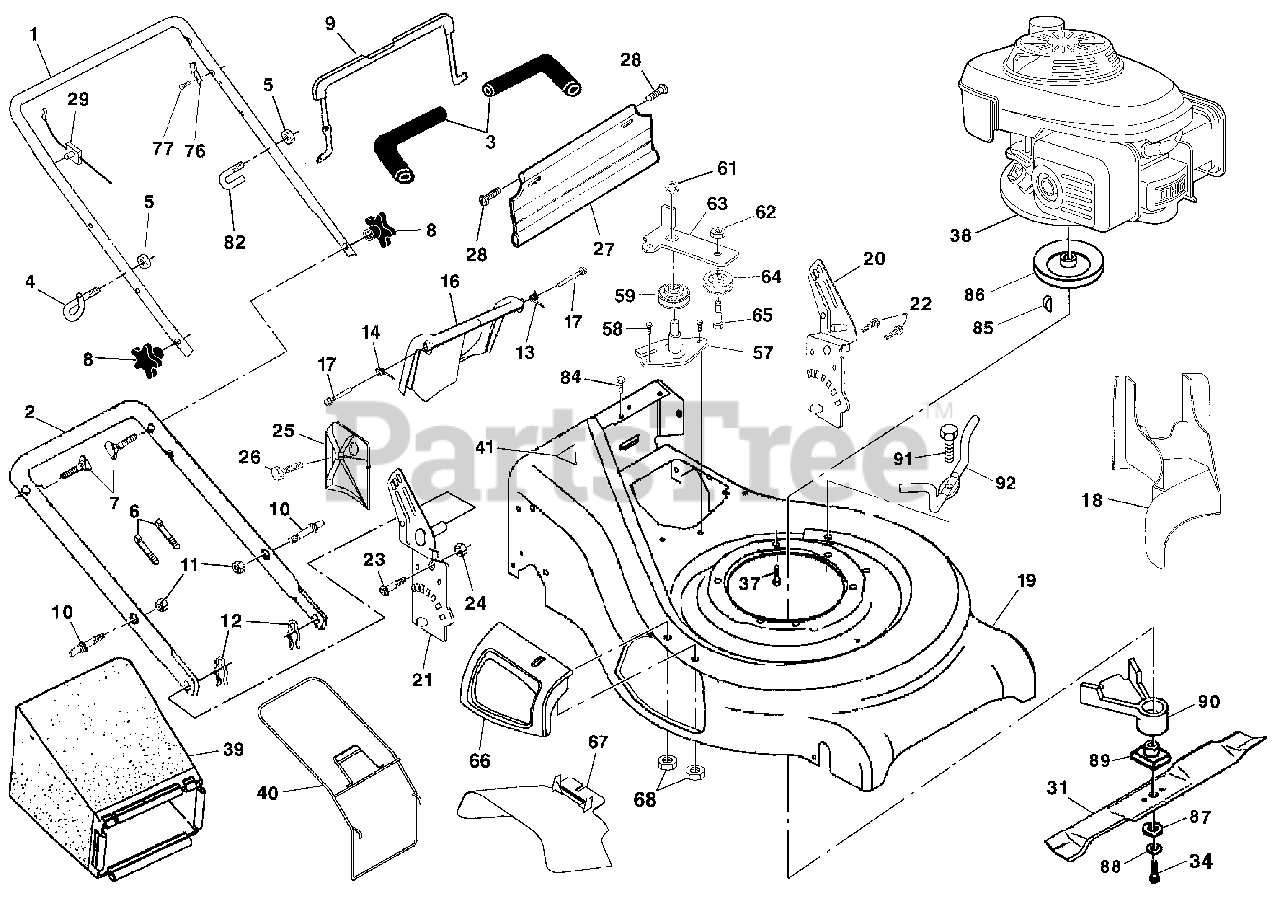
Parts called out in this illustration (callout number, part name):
1	Handle, Upper
2	Handle, Lower
3	Grip, Handle, Foam, Smooth
4	Guide, Rope, Side
5	Nut, Hex Lockwasher Insert 1/4-20
6	Wire, Tie
7	Bolt, Handle 5/16-18 x 1.75
8	Knob, Handle
9	Bail, Flat, Auto-Walk, Orange
10	Bolt, Carriage
11	Nut, Hex, Centerlock 5/16-18 UNC
12	Cotter, Hairpin
13	Spring, Rear Door, LH
14	Spring, Rear Door, RH
17	Bolt, Rear Door
18	Plug, Mulcher
19	Kit, Housing
20	Handle Bracket Assembly, LH
21	Handle Bracket Assembly, RH
22	Screw, Hex Washer Head
23	Bolt, Hex Head 5/16-18 x 5/8
24	Nut, Hex, with Lock Washer Insert 5/16-18
25	Baffle, Side
26	Screw 12 x 5/8
27	Skirt, Rear
28	Screw, Hinge 1/4-20 x 1.25
29	Engine Zone Control Cable
31	Blade, 21"
34	Screw, Hex Head 3/8-24 x 1.38
37	Bolt, Engine
39	Grass Catcher Bag
40	Grass Catcher Frame
41	Danger Decal
57	Bracket Assembly
59	Pulley Assembly, V-Groove
61	Flange Nut
62	Locknut
63	Idler Arm
64	Idler Pulley
65	Shoulder Bolt
66	Mulcher Door Assembly
67	Deflector, Discharge
76	Bracket, Upstop
85	Hi-Pro Key
86	Pulley, Engine
87	Washer, Hardened
88	Lockwasher, Helical Spring 3/8
89	Adapter, Blade
90	Debris Shield
91	Screw
92	Belt Keeper
